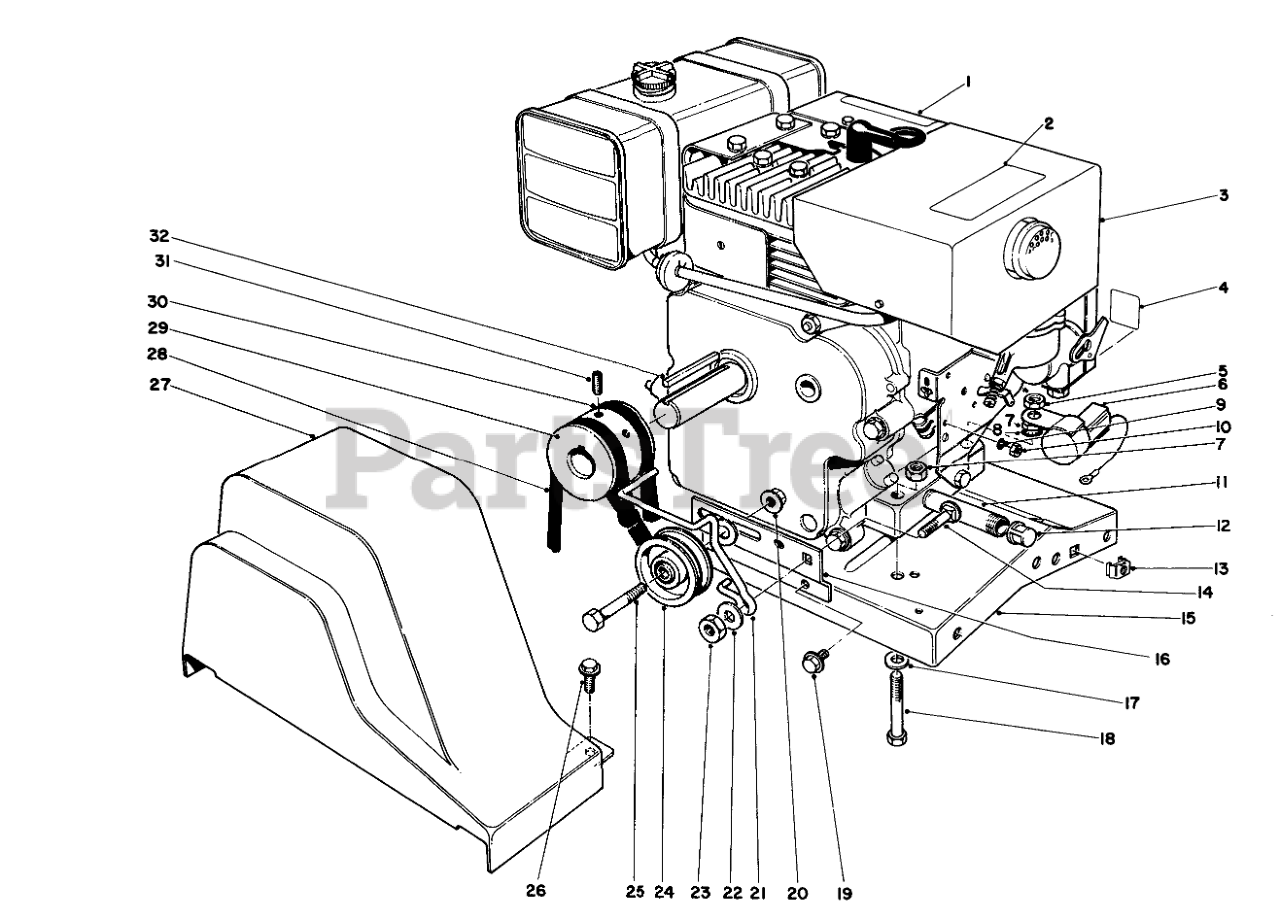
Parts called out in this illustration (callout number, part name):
1	HAZARDS CAUTION DECAL
2	Decal
3	Engine
4	Decal-Choke
5	NUT-HEX, SIDE DEFORM
6	INTERLOCK MODULE
7	NUT-LOCK, NI
8	WASHER-LOCK, INTERNAL
9	WASHER-LOCK/INT
10	NUT-LOCK
11	NIPPLE-PIPE
12	CAP-PIPE
13	RETAINER NUT
14	SCREW-CARR
15	Base-Engine
16	BELT IDLER BRKT
17	WASHER-PLAIN
18	SCREW-HH
19	SCREW-HHFTF
20	NUT-HHF, WHIZ
21	BELT GUIDE
22	WASHER-FLAT
23	NUT-HEX
24	PULLEY B
25	SCREW-HH
26	SCREW-HWH
27	BELT GUARD
28	V-BELT
29	ENGINE PULLEY
30	V-BELT
31	Screw-Set
